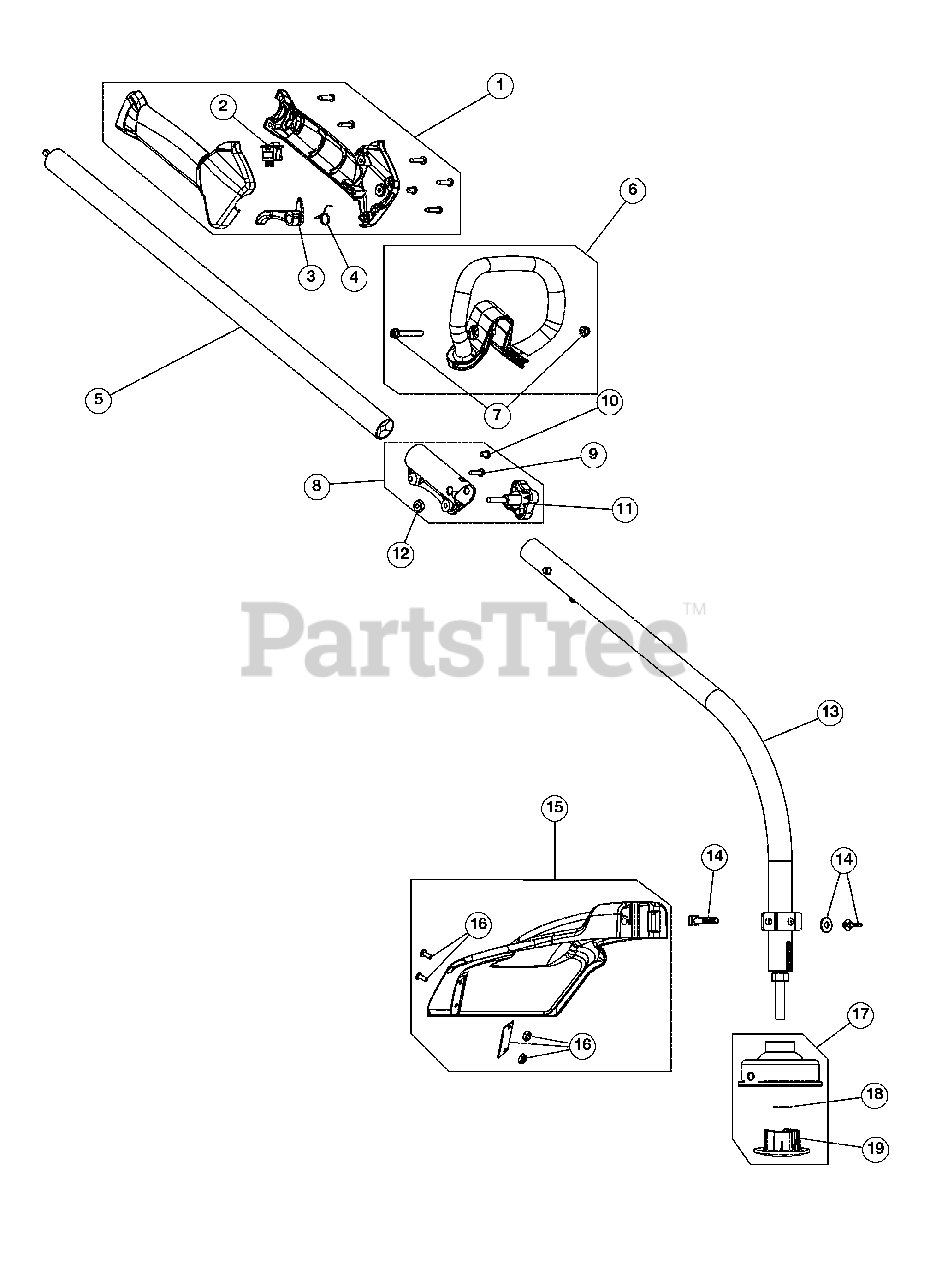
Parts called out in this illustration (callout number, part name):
1	Throttle Housing Assembly (Incl. 2-4)
3	Throttle Trigger
4	Throttle Trigger Spring
5	Upper Shaft Housing Assembly
6	D-Handle (Incl. 7)
7	D-Handle Bolt
8	Split Boom Coupler (Incl. 9-12)
9	Anti-Rotation Screw
11	Adjustment Knob
12	Knob Retainer Nut
13	Lower Shaft Housing Assembly
14	Shield Mounting Hardware
15	Shield Assembly (Incl. 16)
16	Blade Assembly
17	Fixed String Head Assembly (Incl. 18 & 19)
18	Retainer
19	Fixed String Cap
